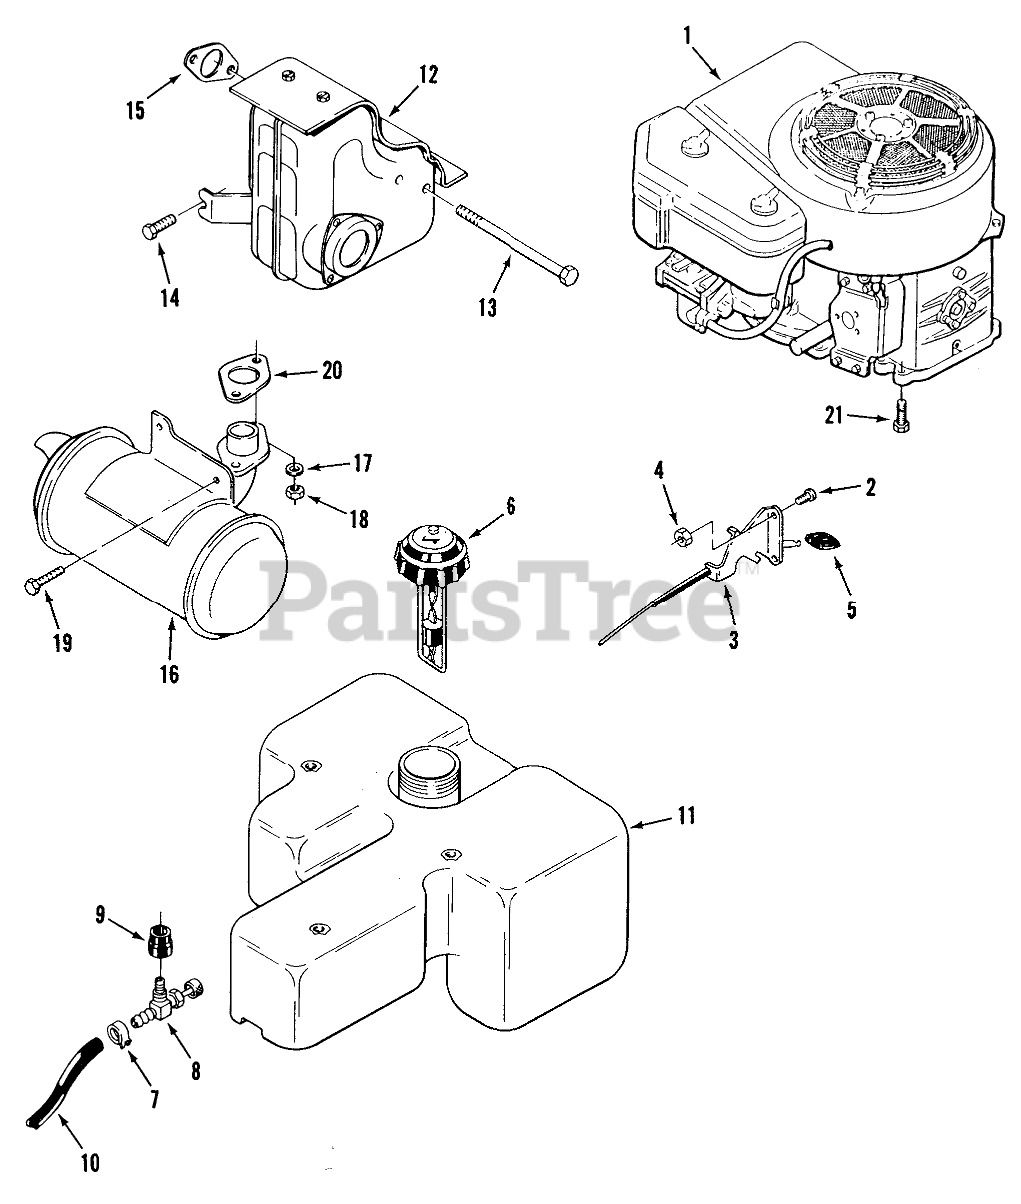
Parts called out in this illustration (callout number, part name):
1	Engine-9 HP-Kawasaki, model FC-290 V
2	Screw
3	Choke/Throttle Control
4	Nut
5	KNOB-THROTTLE
6	ASS'Y-GAUGE CAP
7	Clamp
8	VALVE-FUEL
9	BUSHING
10	Fuel Hose 54 in. (137.2 cm)
11	Fuel Tank
12	Muffler 220-4 (FC-290 V)
14	BOLT-FLANGED
15	GASKET-L MUFFLER
16	Muffler 257-H
17	Lockwasher
18	Nut M8x1.25 257-H
19	HHCS M8X1.25X15
20	OBS GASKET-EXH FC-540V
21	BOLT-FLANGED
